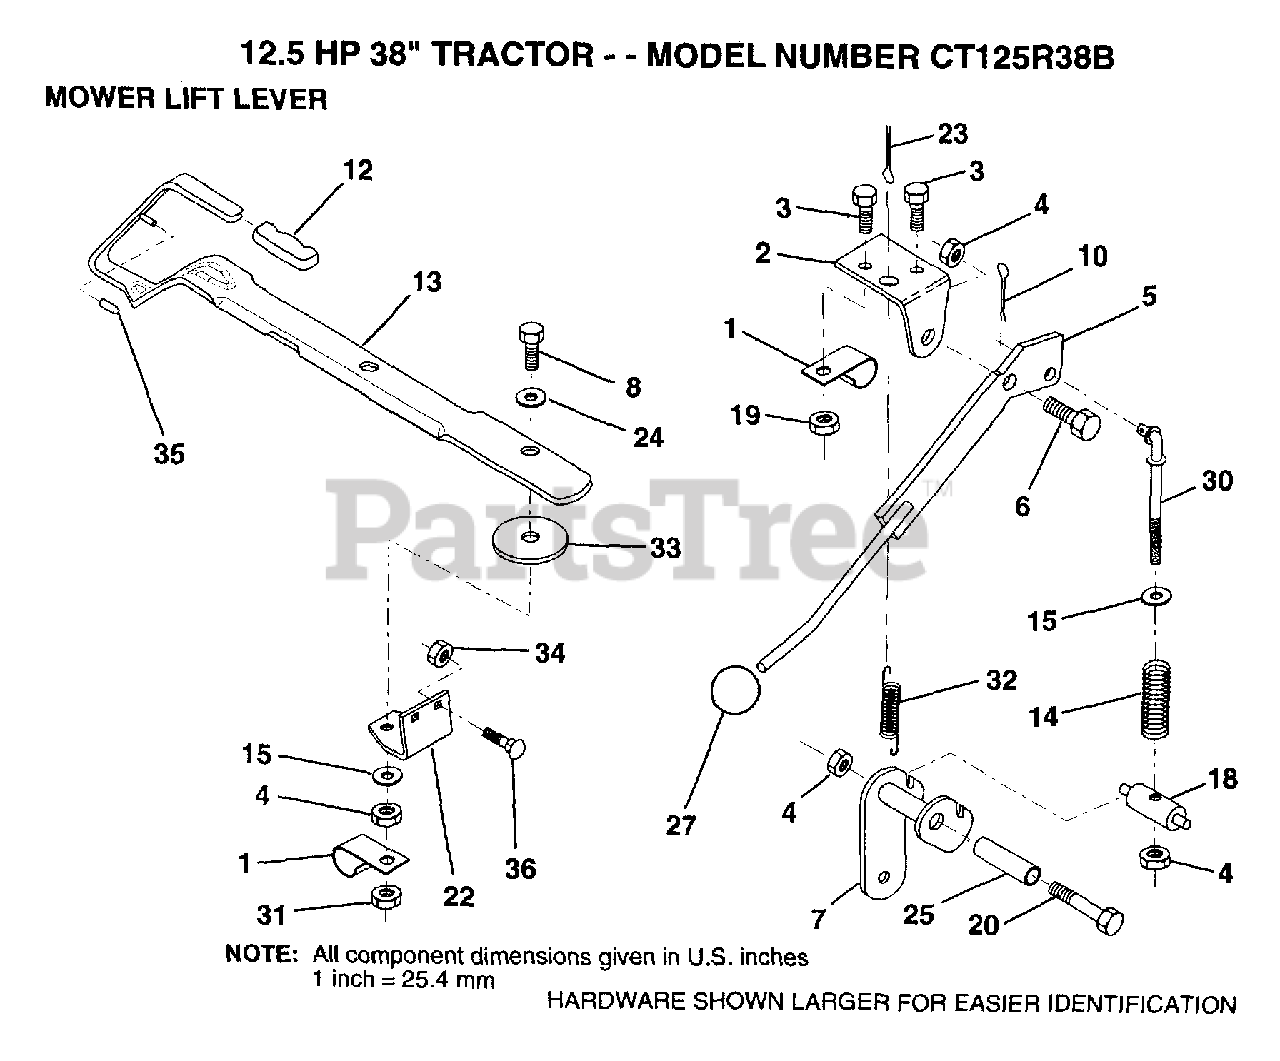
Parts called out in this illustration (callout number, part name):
1	"CLIP,INSULATOR"
2	BRKT CLUTCH
3	BOLT
5	CLUTCH LEVER AS
6	"BOLT, SHOULDER LT"
7	MWR CLUT ARM ASM
8	BOLT
10	COTTER PIN
12	GRIP HANDLE
13	LEVER LIFT LR
14	COMP CLUTCH SPRNG
15	WASHER HYT
18	TRUNNION
20	BOLT
22	LIFT LEVER BRKT
24	WASHER
25	TUBE SPACER
27	KNOB
30	ROD TENSION CLUTC
31	LOCKNUT
32	SPRING EXT
33	WASHER
35	VINYL CAP RED
36	BOLT
